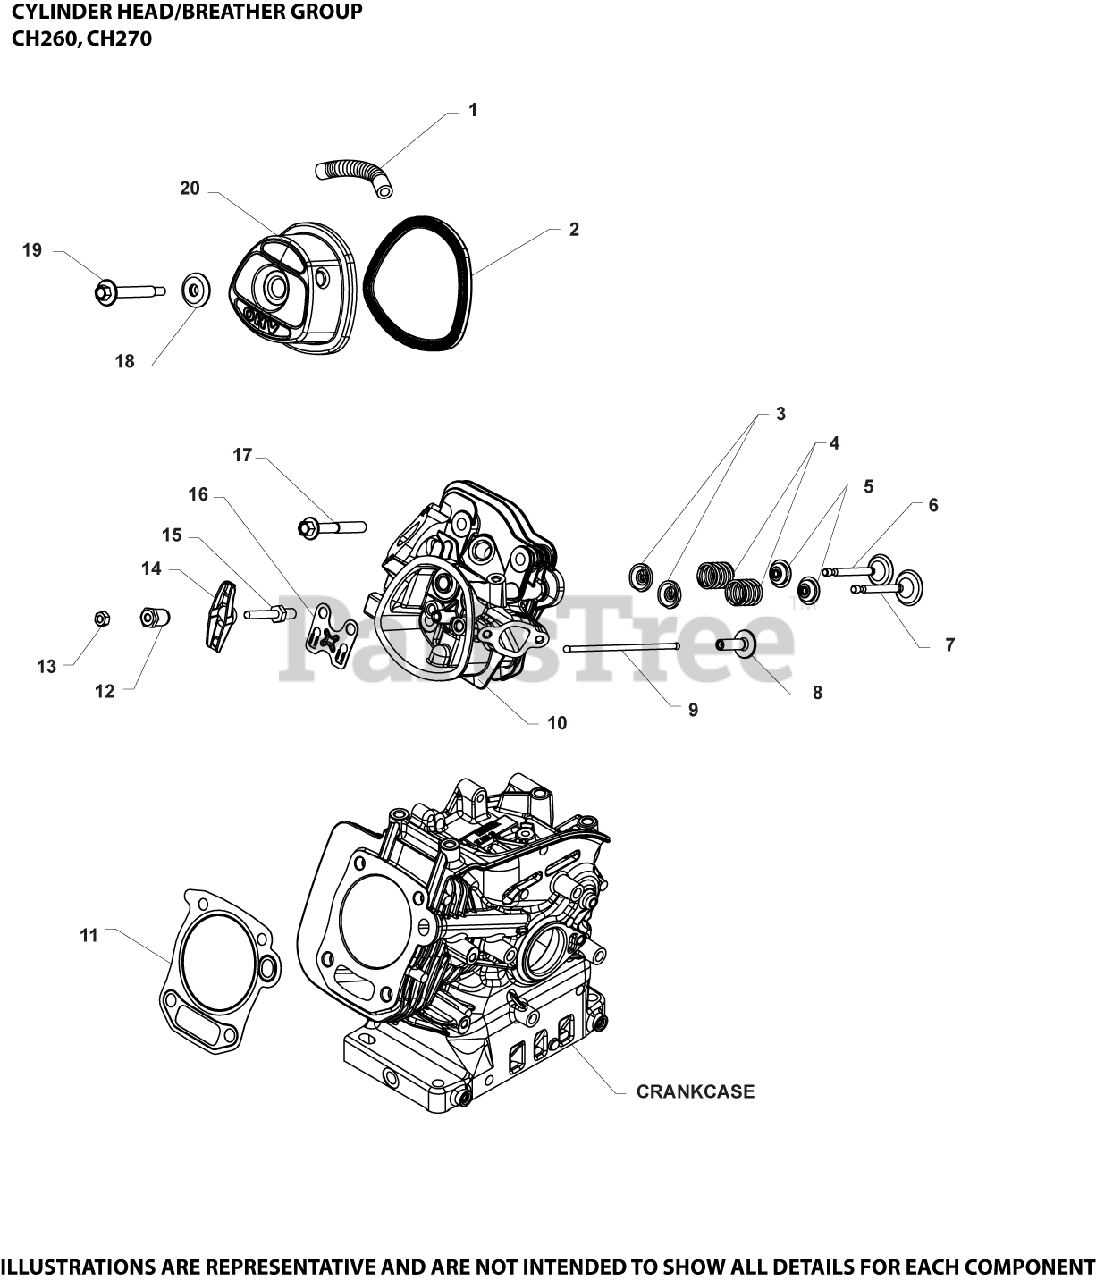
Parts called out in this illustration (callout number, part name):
1	TUBE, BREATHER - (#1812313S)
2	GASKET, VALVE COVER
3	RETAINER, VALVE SPRING
4	SPRING, VALVE
5	SEAL, VALVE STEM
6	VALVE, EXHAUST - USE 17 755 27-S
7	VALVE, INTAKE - (#1775527S)
8	LIFTER, VALVE
9	ROD, PUSH
10	KIT, HEAD ASSEMBLY
11	KIT, HEAD GASKET
12	PIVOT, ROCKER ARM
13	NUT, HEX JAM
14	ARM, ROCKER
15	STUD, ROCKER ARM - (#1407222S)
16	PLATE, PUSHROD GUIDE
17	SCREW, HEX FLANGE CYL HEAD
19	SCREW, VALVE COVER SEAL ASSY
20	KIT, VALVE COVER
